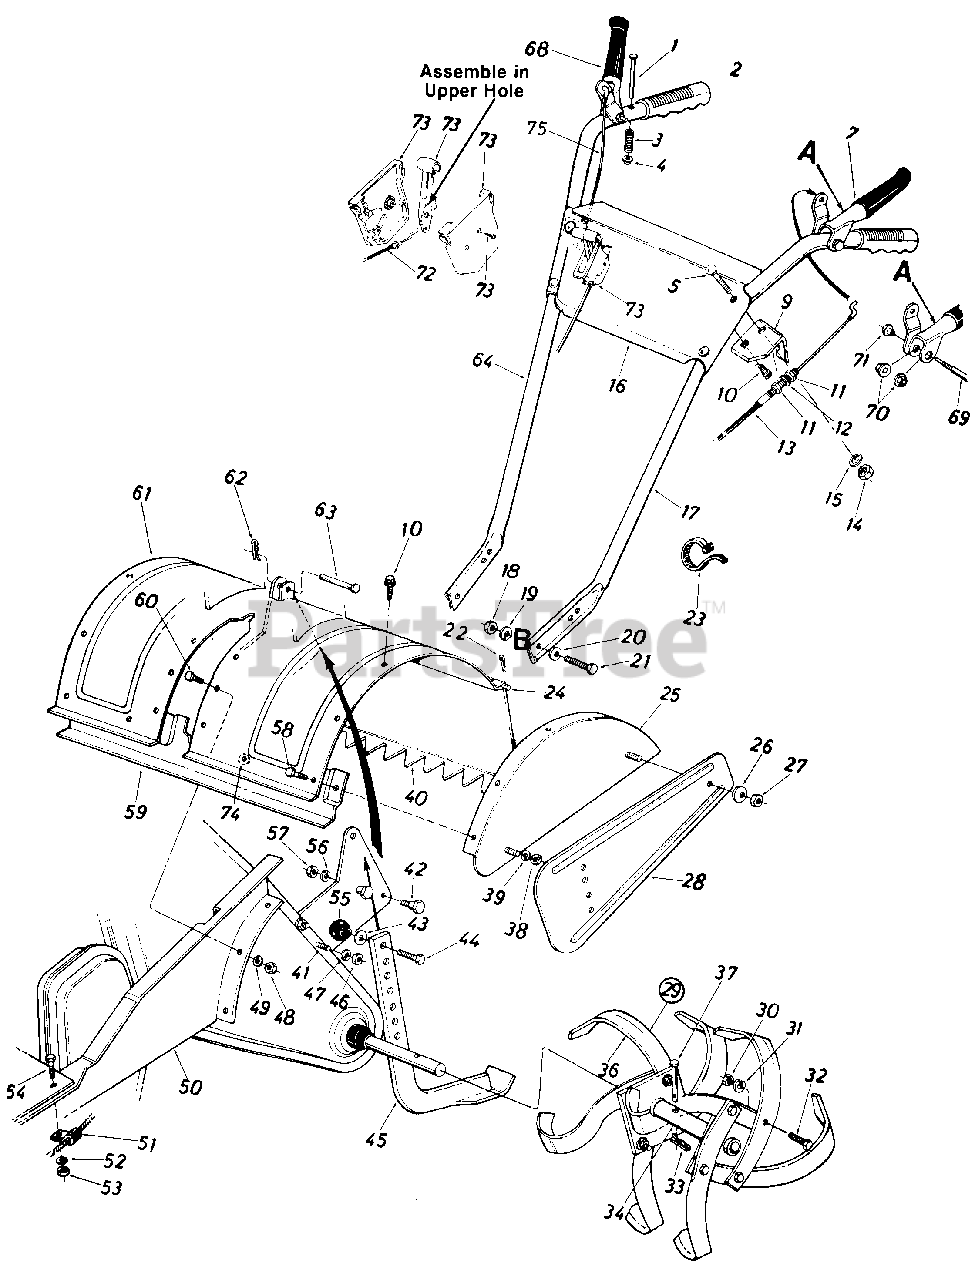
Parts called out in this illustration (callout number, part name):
1	Clevis Pin 1/4" Dia. x 2.25"
2	Grip
3	Compression Spring .33" O.D. x 1.2" Lg.
4	Cap Speed Nut 1/4" Rod
5	Carr. Bolt 5/16-18 x 1.75"'
7	Clutch Grip Ass'y.-L.H.
9	Clutch Cable Bracket
10	Hex Wash. S-Tap Scr. 5/16-18 x .62" Lg.
11	Hex Nut 5/16-24 Thd.
12	L-Wash. 5/16" I.D.*
13	Tine Clutch Control Cable
14	Hex Nut 5/16-18 Thd.
15	L-Wash 5/16" I.D.
16	Handle Panel
19	L-Wash. 3/8" I.D.*
20	Bell-Wash. 3/8" I.D.
21	Hex Bolt 3/8-16 x 1.00" Lg.
22	Cotter Pin 3/32" Dia. x 3/4"*
24	Tiller Flap Rod
27	Hex Nut 5/16-18 Thd.
28	Side Shield
29	Tine Ass'y. Comp.-L.H.
30	Hex Nut 3/8-24 Thd.*
31	L-Wash. 3/8" I.D.
32	Hex Bolt 3/8-24 x 1.25" Lg.
33	Hairpin Cotter
34	Tine Adapter Ass'y.
38	Hex Nut 5/16-18 Thd.
39	L-Wash. 5/16" I.D.
40	Tine Shield Flap
41	Hex Bolt 5/16-18 x 1.0" Lg.
42	Shld. Bolt 1/2" Dia. x .426"
43	Fl-Wash. 3/8" I.D. x 5/8" O.D.
44	Hex Bolt 3/8-16 x 3/4" Lg.
46	Hex Nut 5/16-18 Thd.
47	L-Wash. 5/16" I.D.*
48	Hex Nut 5/16-18 Thd.*
49	L-Wash. 5/16" I.D.
50	Frame Rail-L.H.
51	Clamp 5/16" Dia.
52	L-Wash. 5/16" I.D.
53	Hex Nut 5/16-18 Thd.
54	Hex Bolt 5/16-18 x 3/4" Lg.
55	Ball Knob 1-1/4" Dia. x 3/8-16 Thd.
56	L-Wash. 3/8" I.D.
57	Hex Nut 3/8-16 Thd.
58	Hex Bolt 5/16-18 x .75" Lg.
59	Bracket Reinforcement
60	Hex Bolt 5/16-18 x .75" Lg.
61	Tine Shield Ass'y.
62	Hairpin Cotter
63	Clevis Pin 3/8" Dia.
69	Shoulder Bolt .38" Dia. x 1.53" Lg.
70	Hex Flange Plastic Bearing
71	Shoulder Nut 1/4-20 Thd.
72	Throttle Control Wire
73	Throttle Control Box Ass'y.
74	Bell-Wash. 5/16" I.D.
75	Wheel Drive Cable
